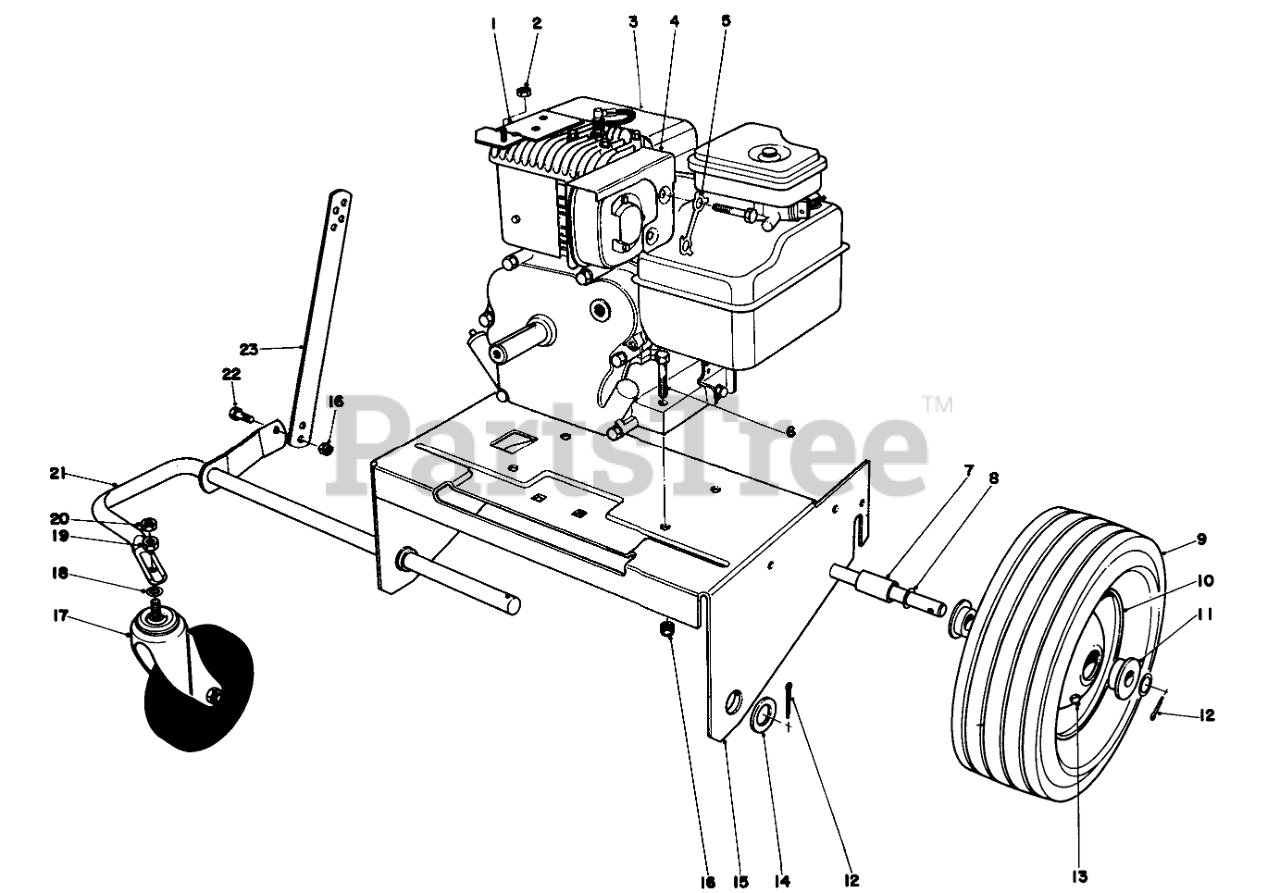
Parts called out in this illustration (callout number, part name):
1	MTG BRKT WA B
2	Locknut
3	Engine
4	HEAT SHIELD
5	Lock Strip
6	SCREW-HH
7	SPACER-AXLE
8	WASHER
9	3.50X10 SEMIPNEU TIRE
10	Wheel & Tire Assembly (Incl. Ref. #9, 11 & 13)
11	BUSHING
12	PIN-COTTER
13	FITTING-GREASE
14	WASHER-FLAT
15	BLWR ENG MTG PLT WA
16	NUT-LOCK, CONE
17	CASTER
18	Lockwasher
19	NUT-HH
20	1/2-13 CONELOCK NUT
21	FRT WHL SUPPORT WA
22	SCREW-HH
23	HT ADJ BAR
